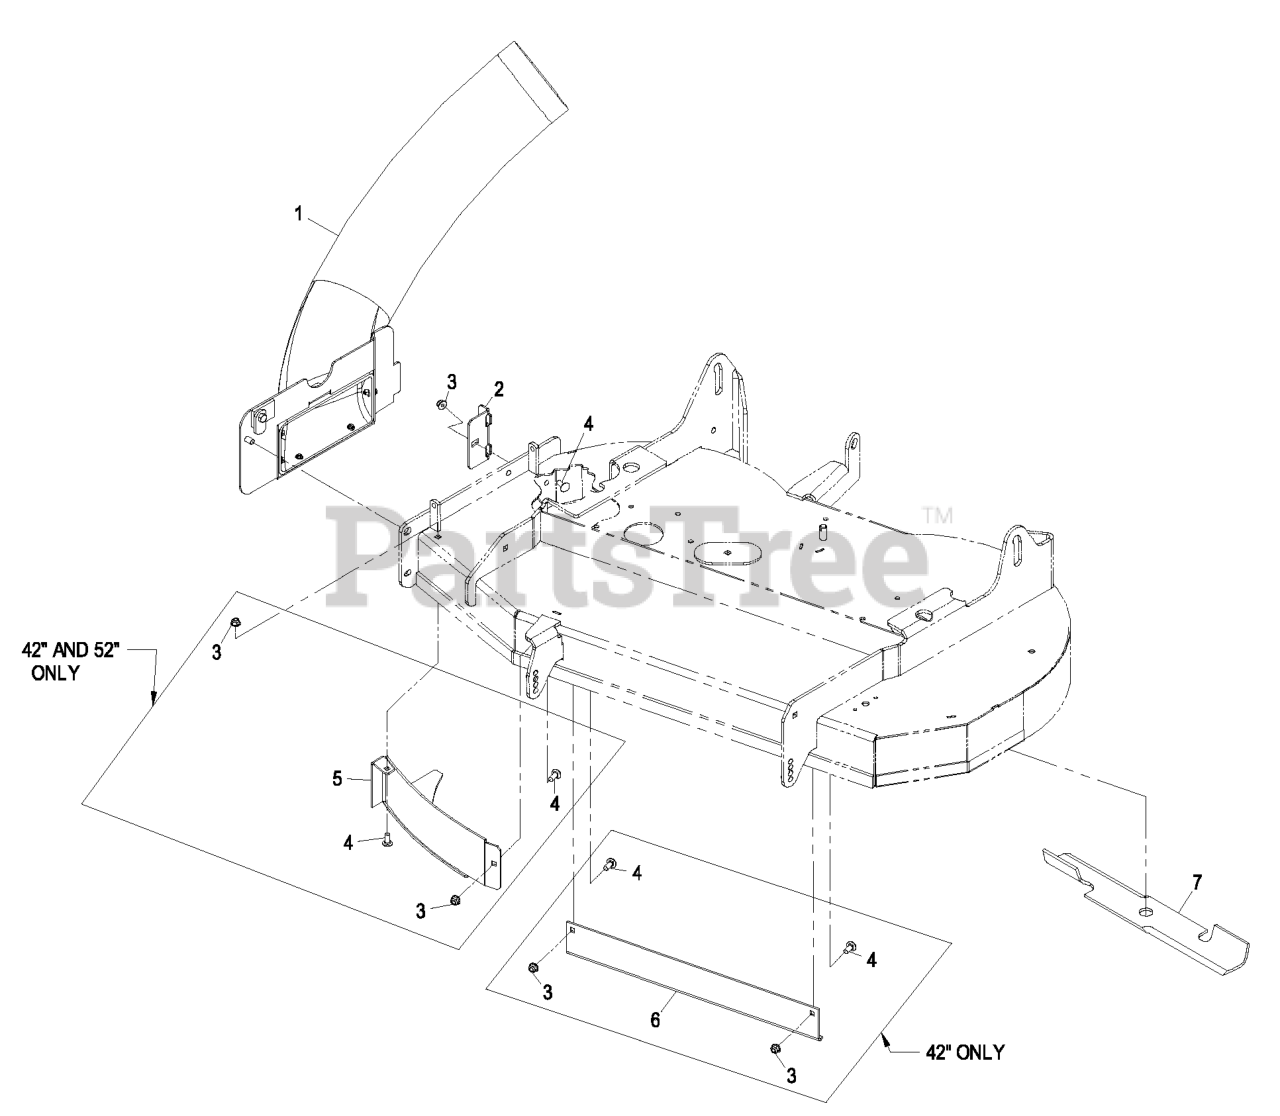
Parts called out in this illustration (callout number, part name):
1	ASM,TUBE AND FRAME
2	BRACKET,42 BAGGER MOUNT
3	NUT-HF, NI
4	SCREW-CARR
5	WLD,DISCHARGE BAFFLE
6	BAFFLE,CENTER BAGGER
7	Blade, Bagger 42"
